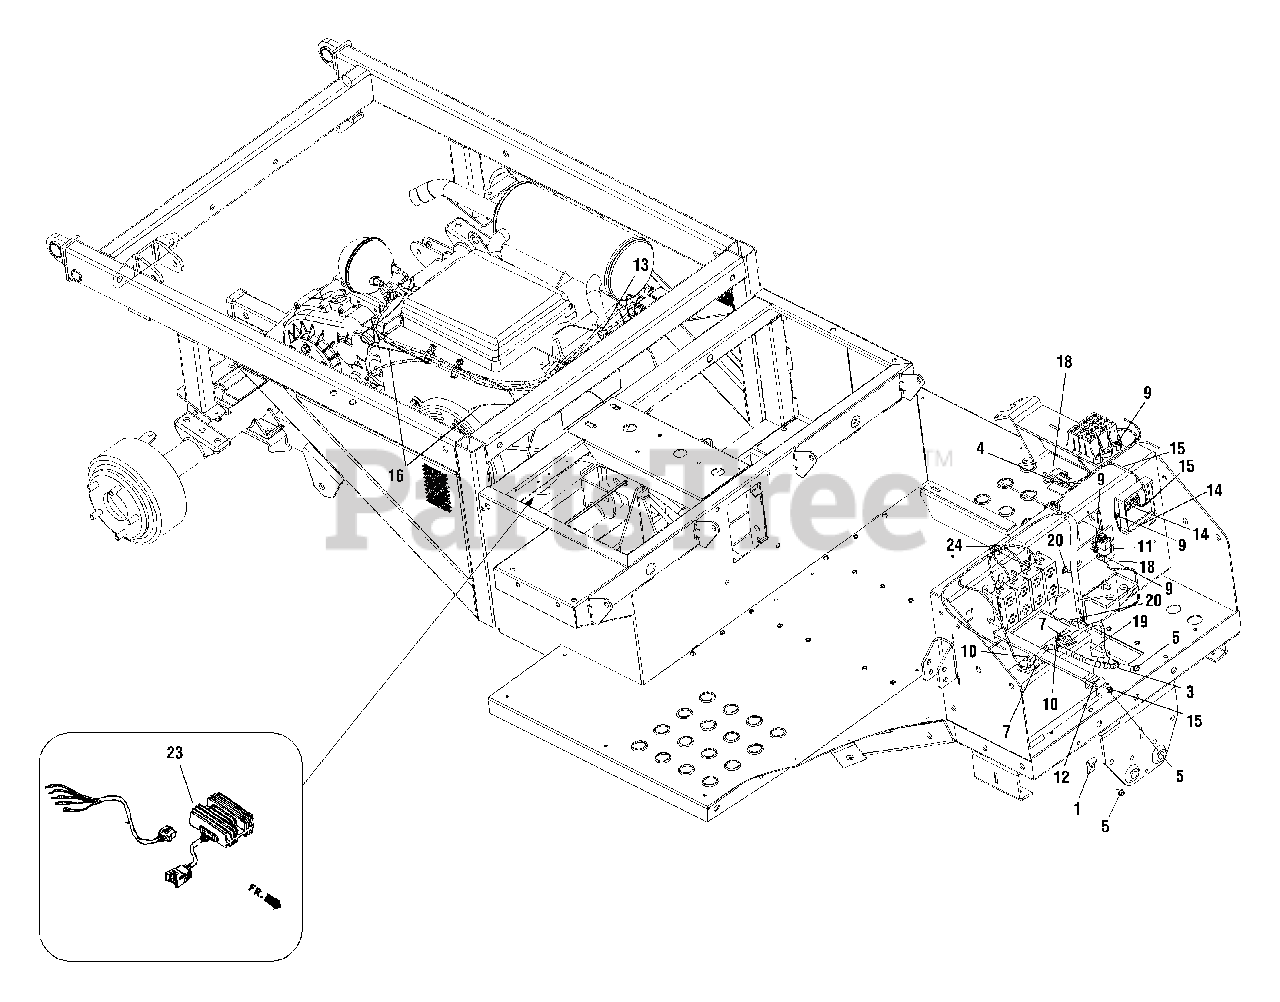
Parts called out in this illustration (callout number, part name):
1	Bracket, Retainer Hook
3	Harness Assembly, Motor Ground
4	Screw, 1/4-20 x .50
5	Screw, Self-tapping, 1/4-20 x 0.500
7	Screw, Hex Carriage, 1/4-20 x .75
9	Screw, #10-24 x 0.75
10	Nut, Hex Sems, 1/4-20
11	Cover, Protective
12	Strap, Battery
13	Cable Tie, 3/16 x .05 x 7.4
14	Control, Shaft
15	Harness, Utility Main
16	Harness, Motor
18	Switch
19	Battery
20	Cable Tie, .19 x 8.39 Tree Mount
23	Rectifier Assembly, Regulator (20A)
24	Retainer Clip, .250 x .267
